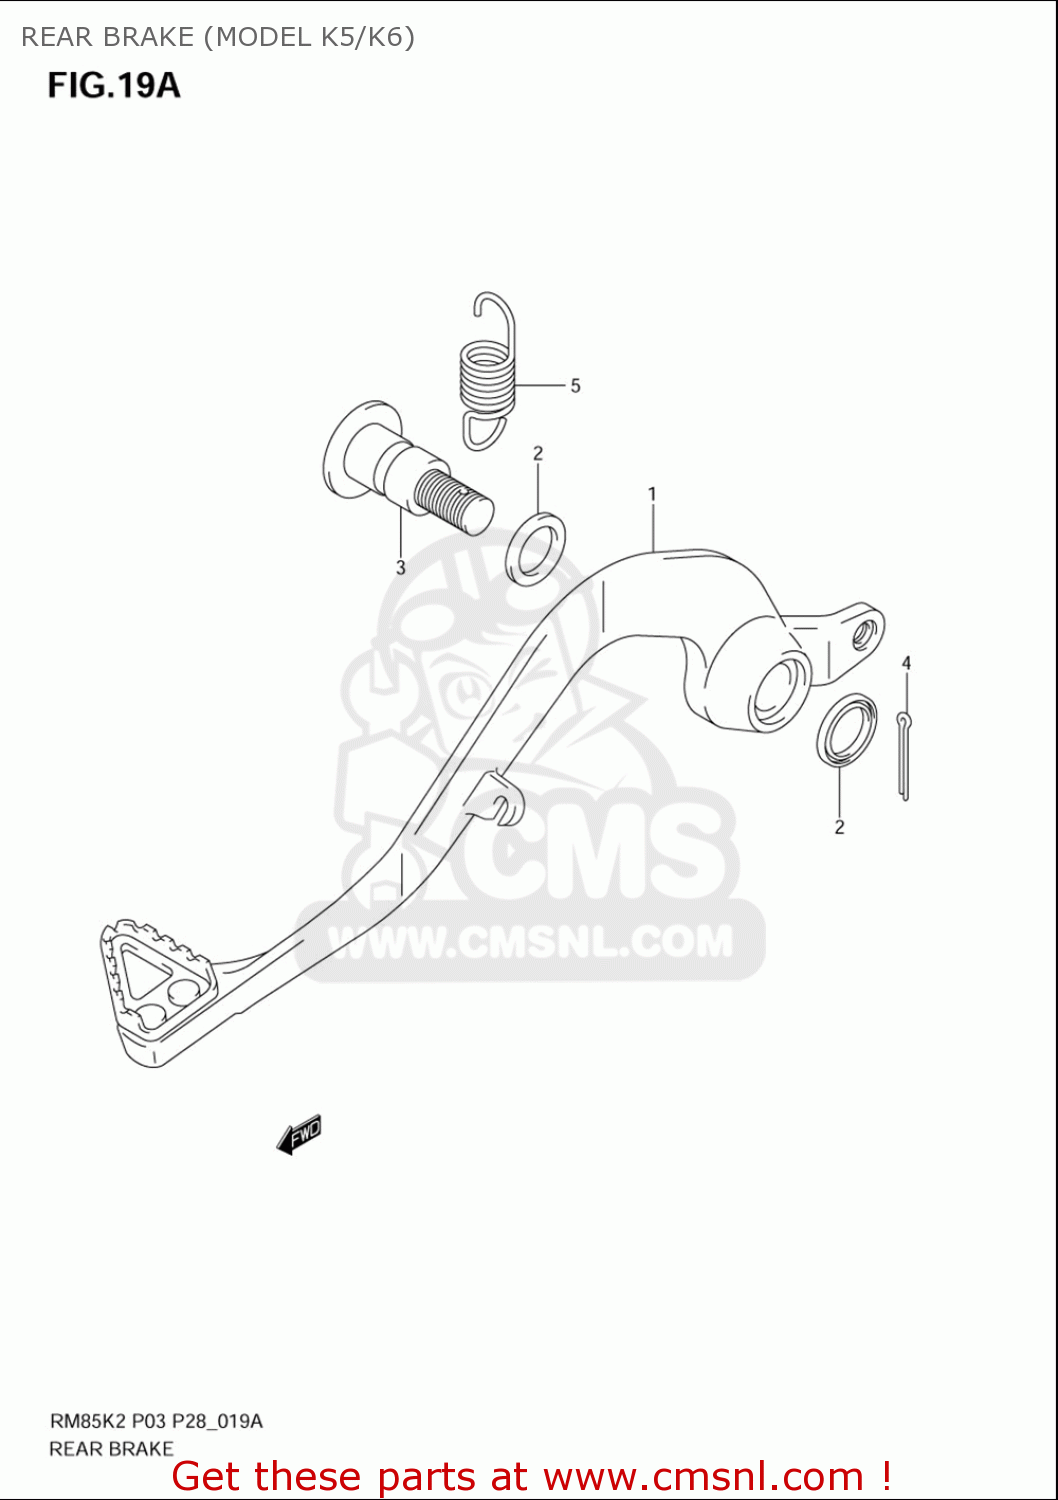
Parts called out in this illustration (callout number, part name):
1	PEDAL ASSY,BRAKE
2	SEAL,OIL(15X21X3)
3	SHAFT,BRAKE PEDAL
4	PIN
5	SPRING
